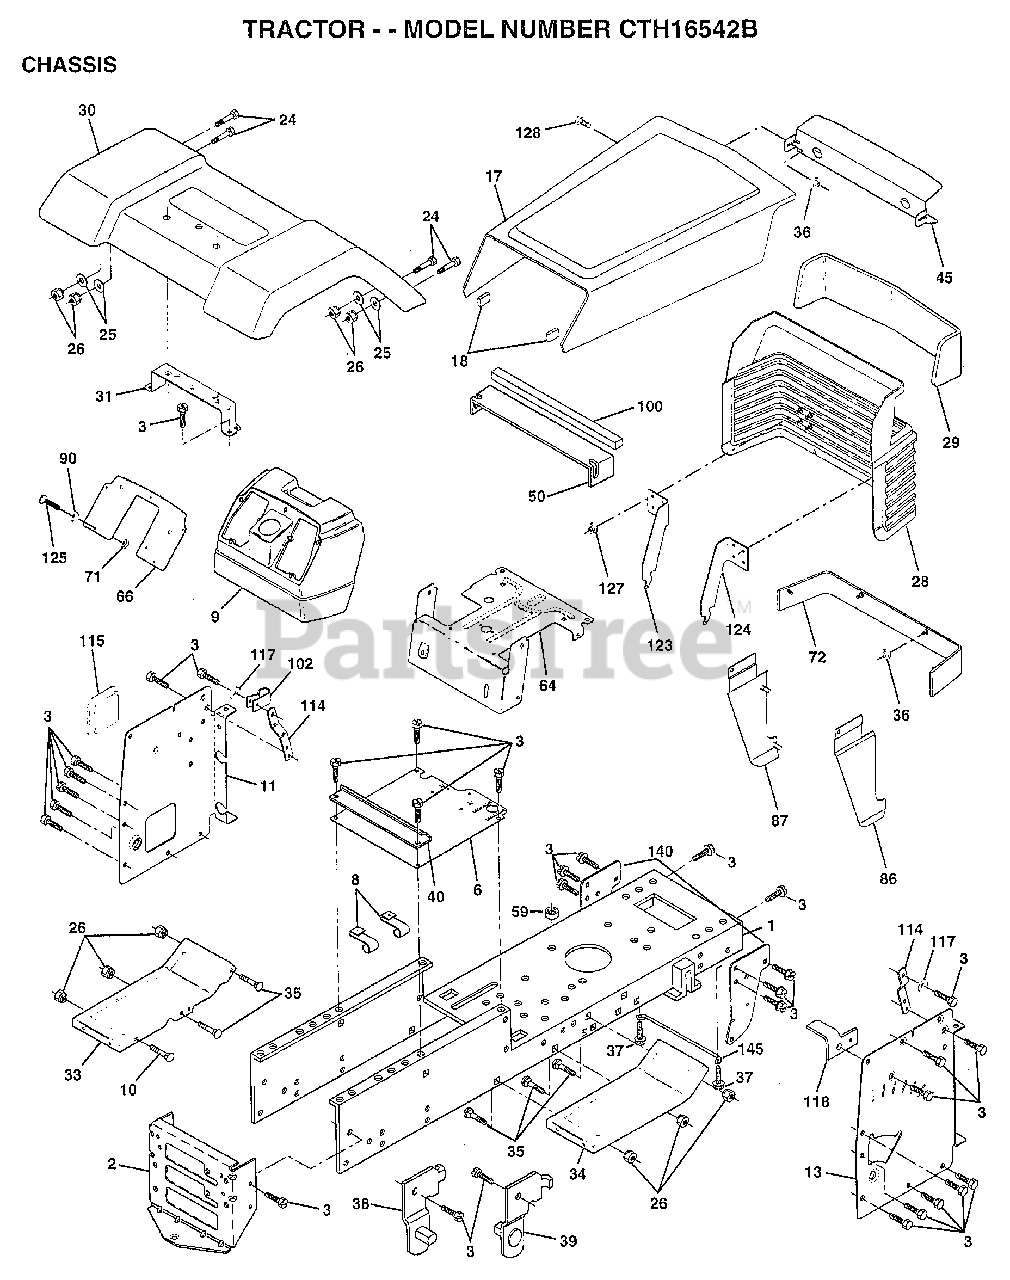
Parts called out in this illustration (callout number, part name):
3	SCREW
6	SADDLE
8	"CLIP,INSULATOR"
9	DASH.PLASTIC.BLK
11	PANEL.DASH.LH.
13	PANEL.DASH.RH.
17	HOOD/GRILLE ASM
24	BOLT
25	WASHER
26	NUT
28	GRILLE ASM WELD
31	BRACKET SUPT FEND
33	FOOTREST.LH.LT/GT
34	FOOTREST.RH.LT/GT
35	BOLT
36	PAL NUT LT
38	BRACKET ASM LH
39	BRACKET ASM RH
40	SPACER FENDER LT
45	BEZEL.LIGHT.SLVR
50	"BAFFLE,HOOD"
64	DASH.LOWER.LT
66	PLATE.SLKSCR.O.M.
71	NUT HXKEP 1/4X20
72	STRAP FENDER ASM
86	PANEL SIDE RH ASM
87	PANEL SIDE LH ASM
90	WASHER PM
100	FOAM-STRIP LT
102	CLIP T
114	BRACKET.SUPT.DASH
115	COVER ACCESS
117	WASHER.SERRATED.
118	BRACKET.CLUTCH.MC
123	BRACKET.PICK.LH.
124	BRACKET.PICK.RH.
125	SCREW
127	PAL NUT
128	SCREW SPECIAL
140	BRKT SUSPENSION
145	"ROD POVOT,CHASSIS"
